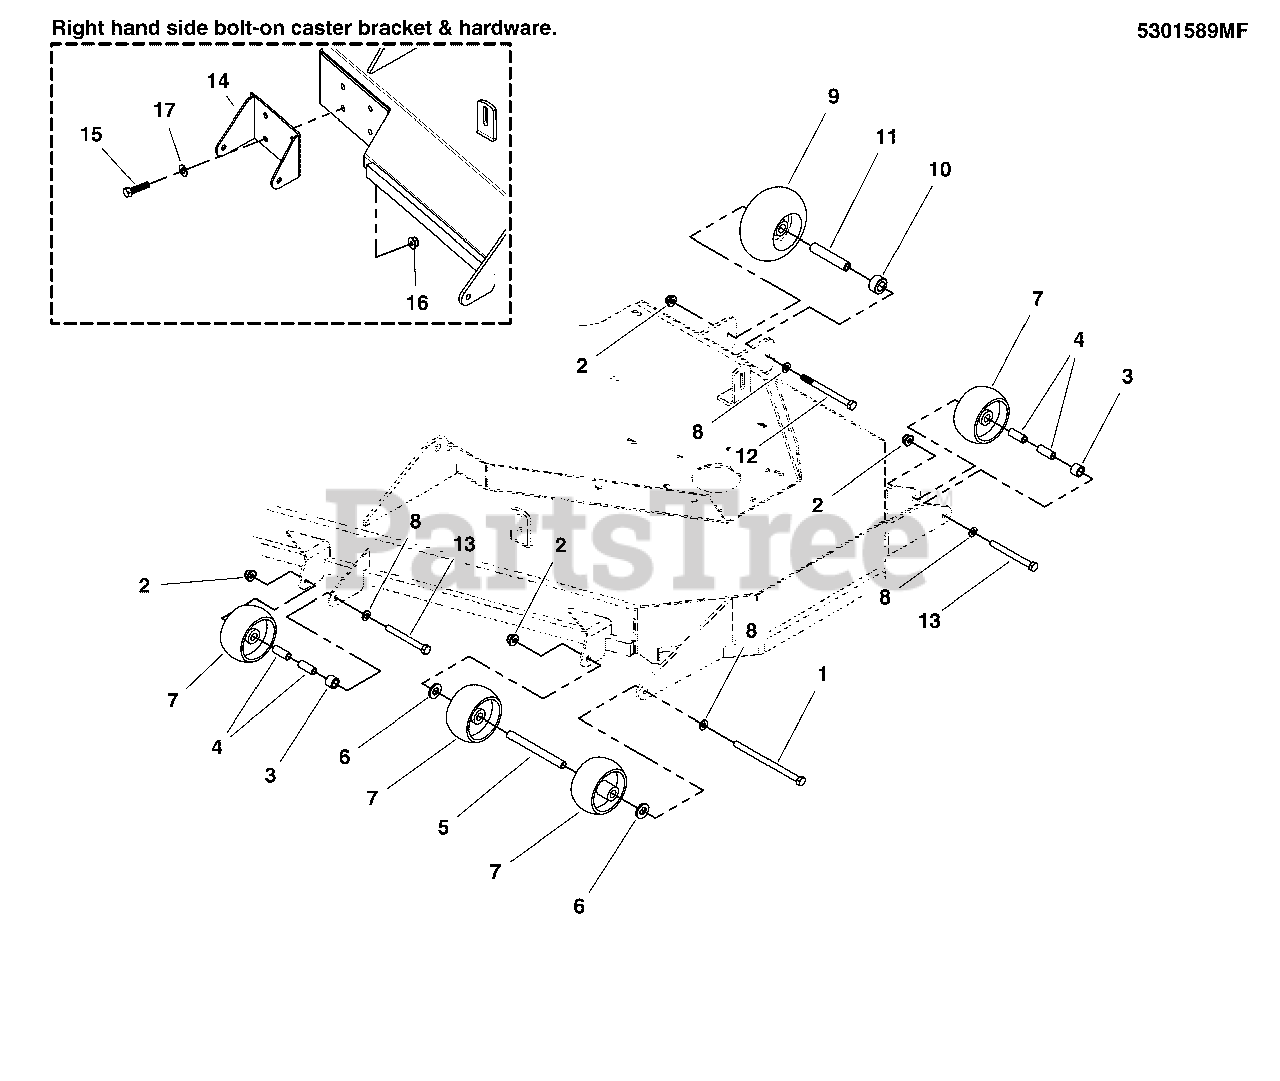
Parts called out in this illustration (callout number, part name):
1	BOLT, 3/8-16 X 6 GD5 YZ
2	NUT, 3/8-16 HEX NYLOCK FLANGE
3	SPACER, .51 X .75 X .56
4	SPACER, .38 X .50 X 1.25
5	SPACER, .38 X .50 X 5.06
6	WASHER, 1/2 GD9 YZ
7	WHEEL- 2.00 WIDE 3.88 DIA 0.531ID POLY
8	WASHER, 5/16 SAE
9	GAUGE WHEEL-2.70
10	SPACER, .64 X 1.13 X .63
11	SPACER, .38 X .63 X 3.25, YZ
12	BOLT, 3/8-16 X 4-1/2 GD5 YZ
13	BOLT, 3/8-16 X 3-1/2 GD5 YZ
14	PLATE, BRACKET, ANTI SCALP - RED
15	BOLT, 3/8-16 X 1 GD5 YZ
16	NUT, 3/8-16 HEX NYLOCK FLANGE
17	WASHER, 3/8 SAE
